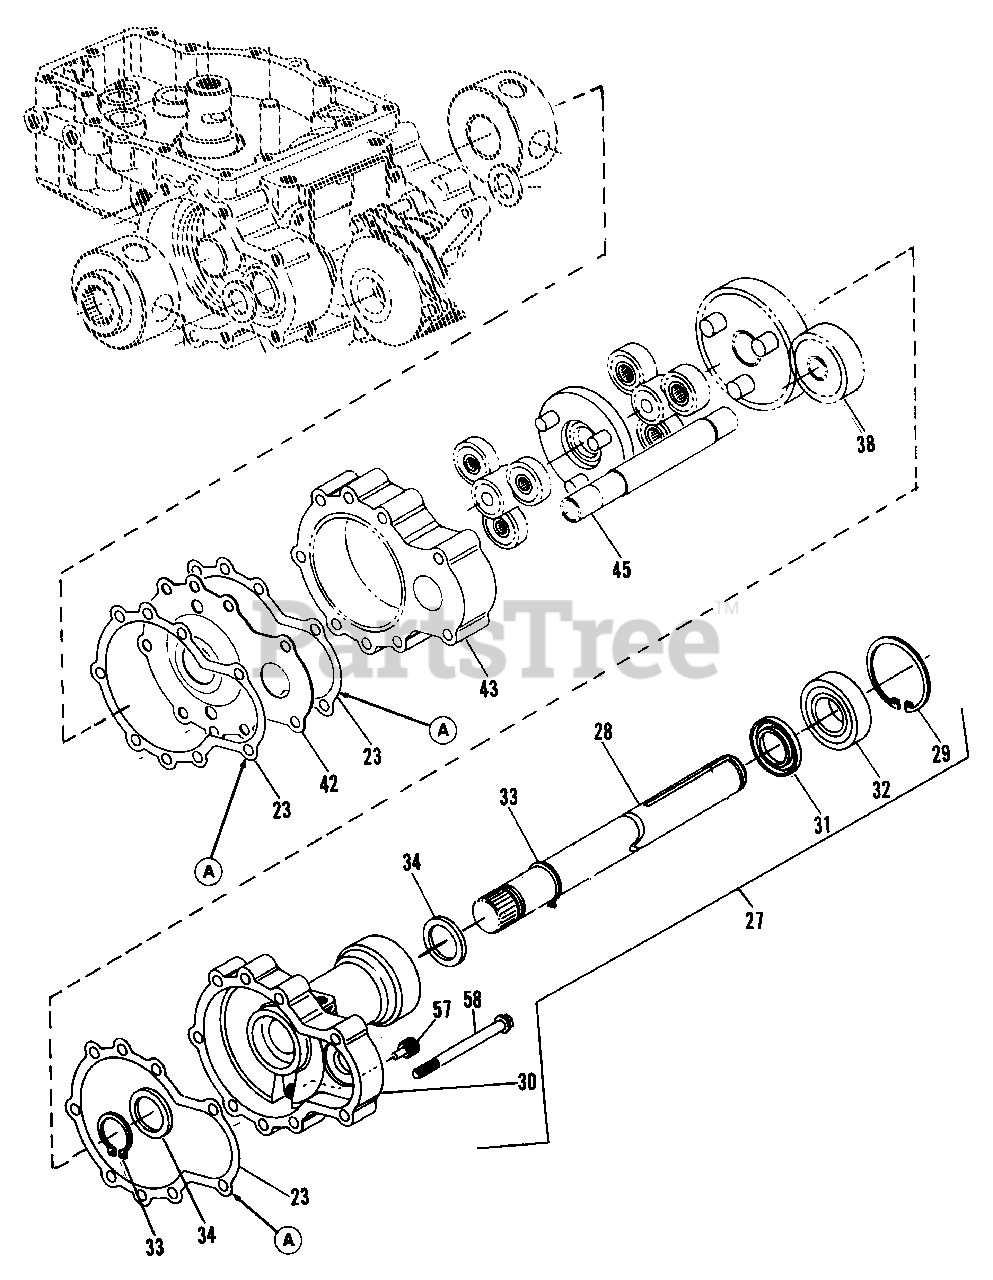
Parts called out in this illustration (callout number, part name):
23	GASKET, Axle Housing
27	AXLE HOUSING, R.H. (Incl. Ref. Nos. 28-34)
28	SHAFT, Axle
29	RETAINING RING, Internal
30	HOUSING, Axle, R.H.
31	UPSEAL, Radial
32	BEARING, Ball
33	RING, Retainer
34	WASHER, Thrust
38	LOCKGEAR, Diff.
42	PLATE, Wear
43	RING GEAR, 54 Tooth
45	BRAKESHAFT, R.H.
57	PLUG, Magnetic
A	GASKET OVERHAUL KIT (Incl. Ref. Nos. 20, 23 & 25)
